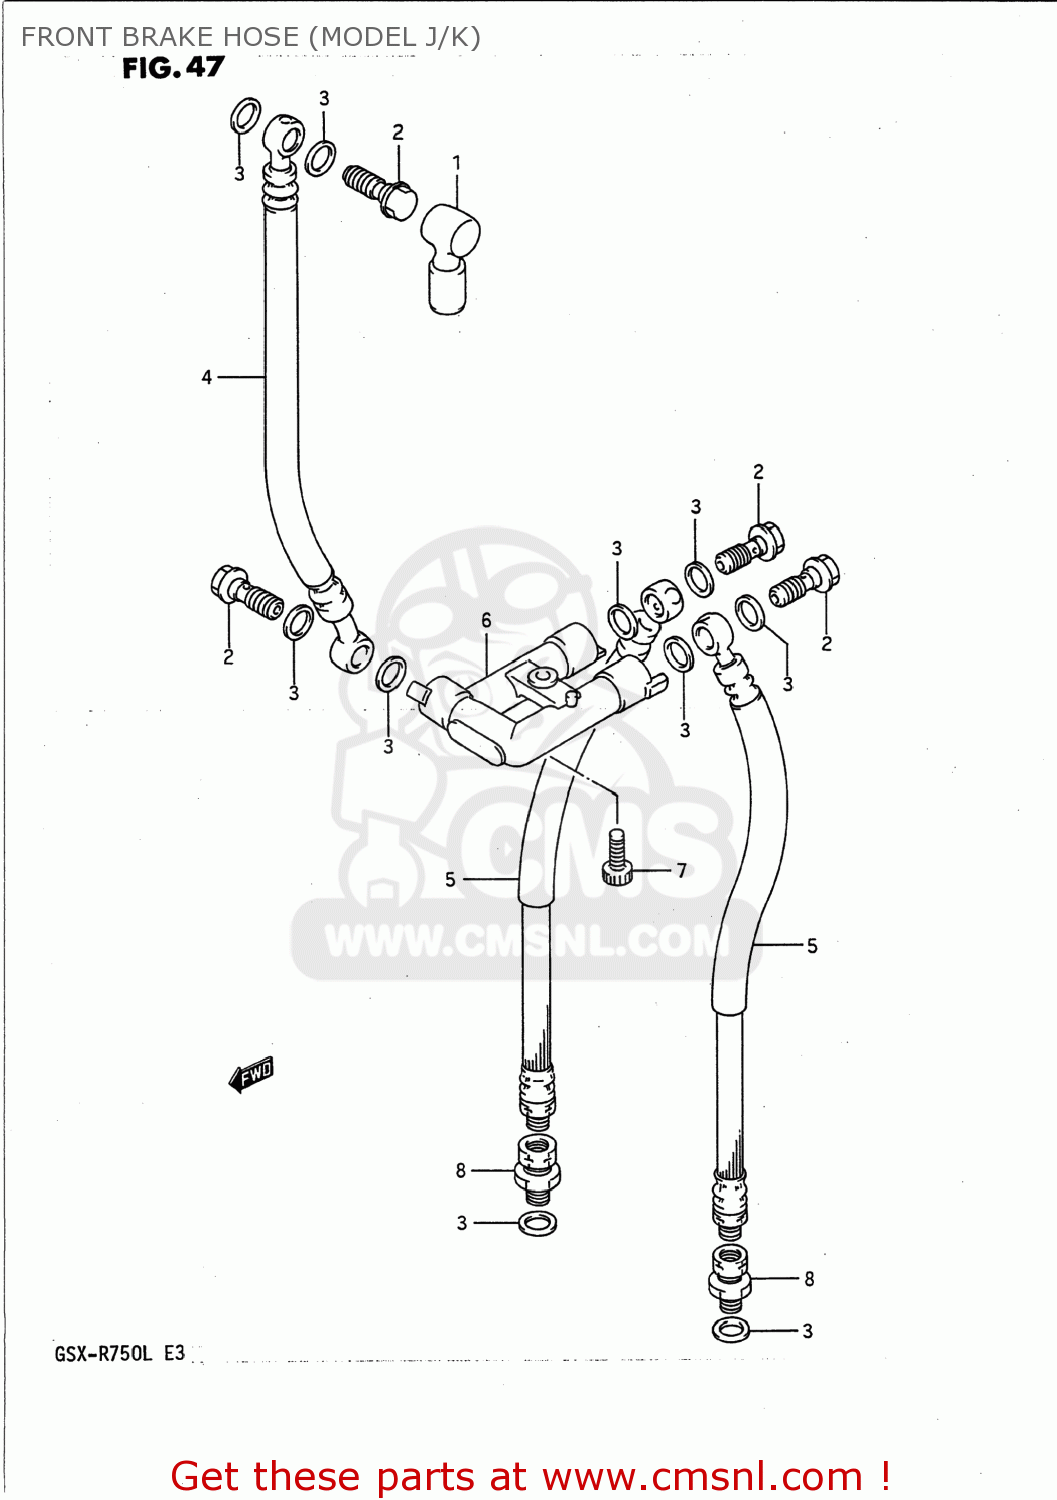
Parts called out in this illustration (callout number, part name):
1	BOOT,MASTER CYLINDER
2	BOLT UNION
3	WASHER(10X15X1.5)
4	HOSE,FRONT BRAKE
5	HOSE COMP,FRONT BRAKE
6	JOINT,BRAKE HOSE
7	BOLT
8	ADAPTER,BRAKE HOSE
